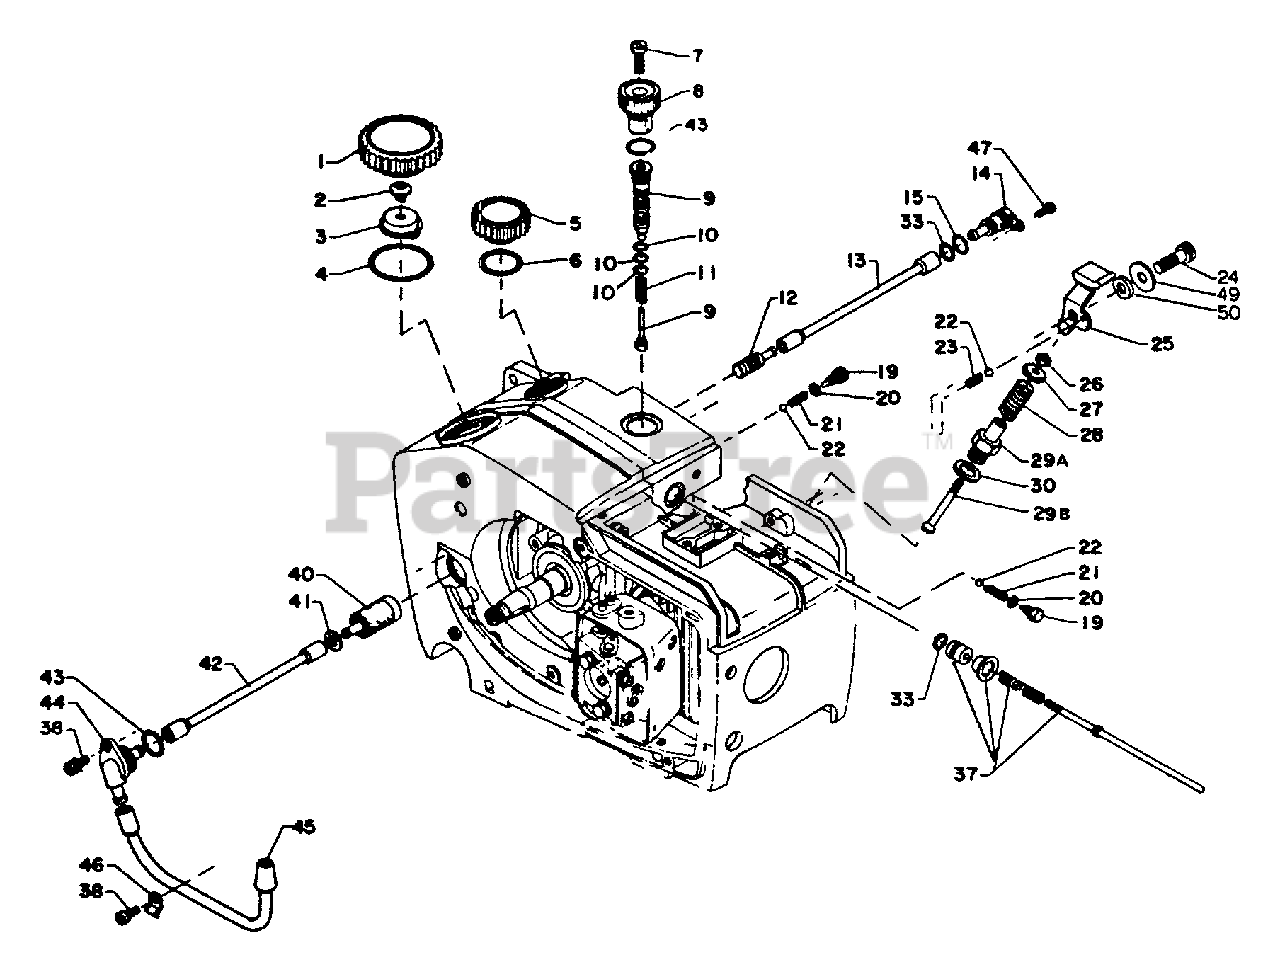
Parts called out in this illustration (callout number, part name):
1	CAP
3	HOLDER, VENT
4	O-RING - 29
5	CAP, OIL TANK
6	O-RING - 25
7	LABEL - FUEL MIX
7	SCREW
8	LABEL - CHAIN OIL
8	DIAL, AUTO-OILER
9	AUTO-OILER ASSY
10	O-RING - 5
12	FILTER, OIL
13	PIPE, OIL - OUTER
14	CONNECTOR
15	O-RING - 7
19	ADAPTER, OIL PUMP
21	SPRING, VALVE
22	BALL
24	SCREW - 5X15
25	LEVER, DECOMPRESSION
25	DECOMPRESSION ASSY
28	SPRING, VALVE
33	O-RING - 6
37	PUMP ROD ASSY
38	SCREW - 4X10
40	FILTER, FUEL
41	WASHER - 5
42	PIPE - FUEL
43	O-RING - 12
44	CONNECTOR, PIPE
45	PIPE, FUEL - OUTER
47	SCREW - 3X8
49	WASHER - 5
